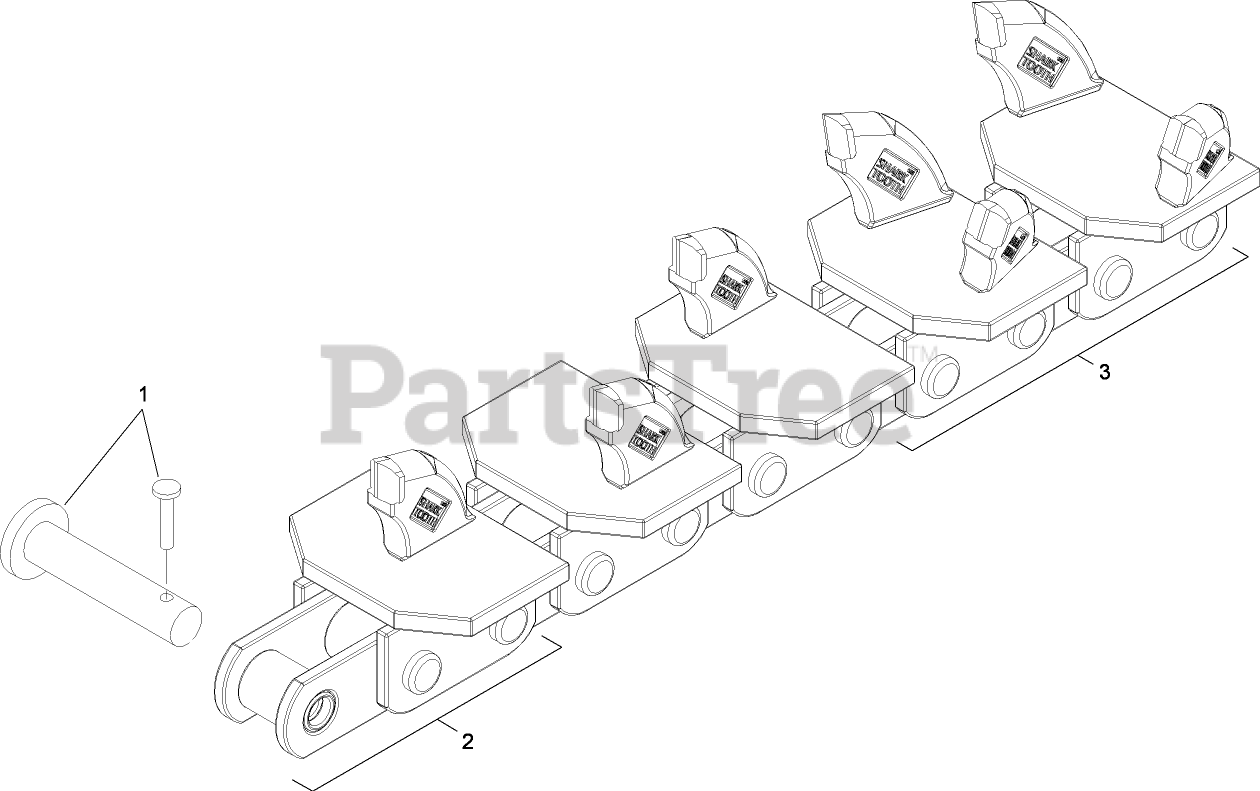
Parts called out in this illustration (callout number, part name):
1	PIN AND KEY KIT
2	STATION-REPAIR, SINGLE
3	STATION-REPAIR, 4 INCH
